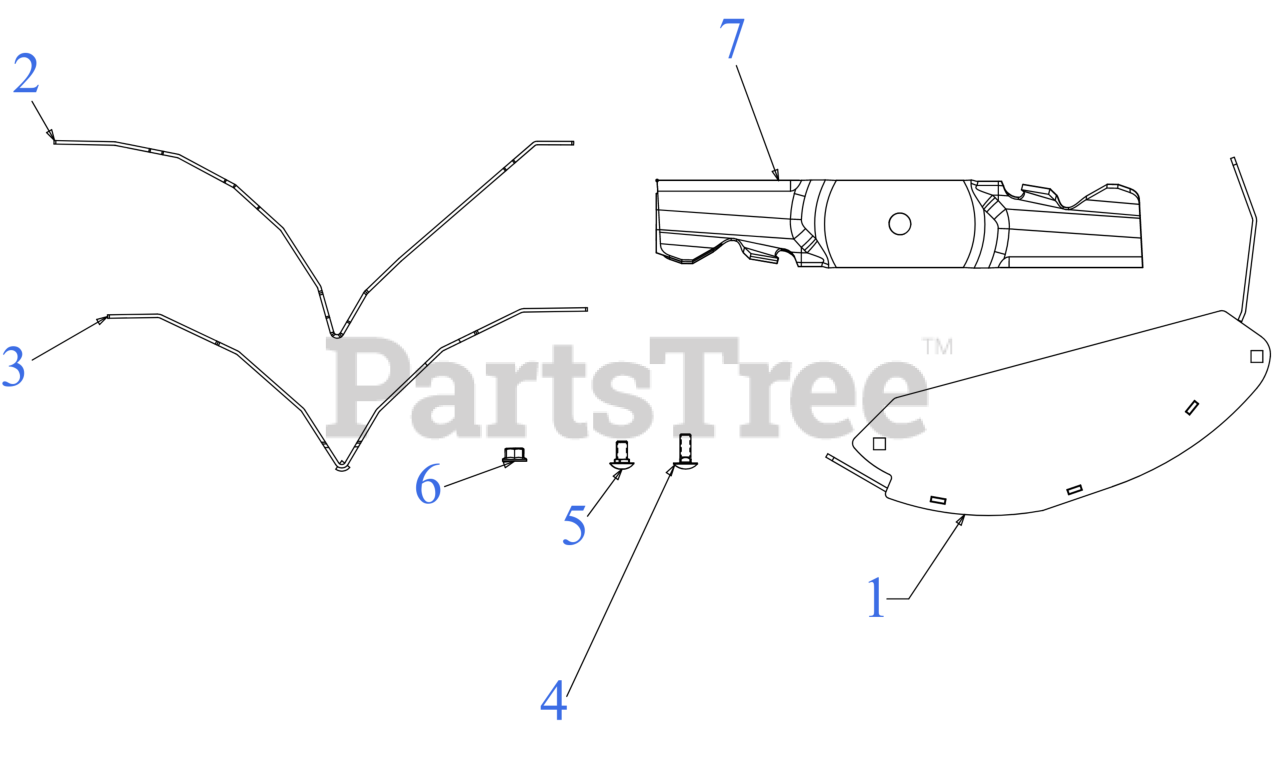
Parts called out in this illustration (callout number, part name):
1	48" DISCHARGE MULCH BAFFLE
3	MULCH BAFFLE (LEFT)
4	CARRIAGE BOLT 3/8-16 x 1.00 GR5
5	CARRIAGE BOLT 3/8-16 x .75
6	NUT-CTRLCK FLG HEX
7	17" XTREME BLADE
